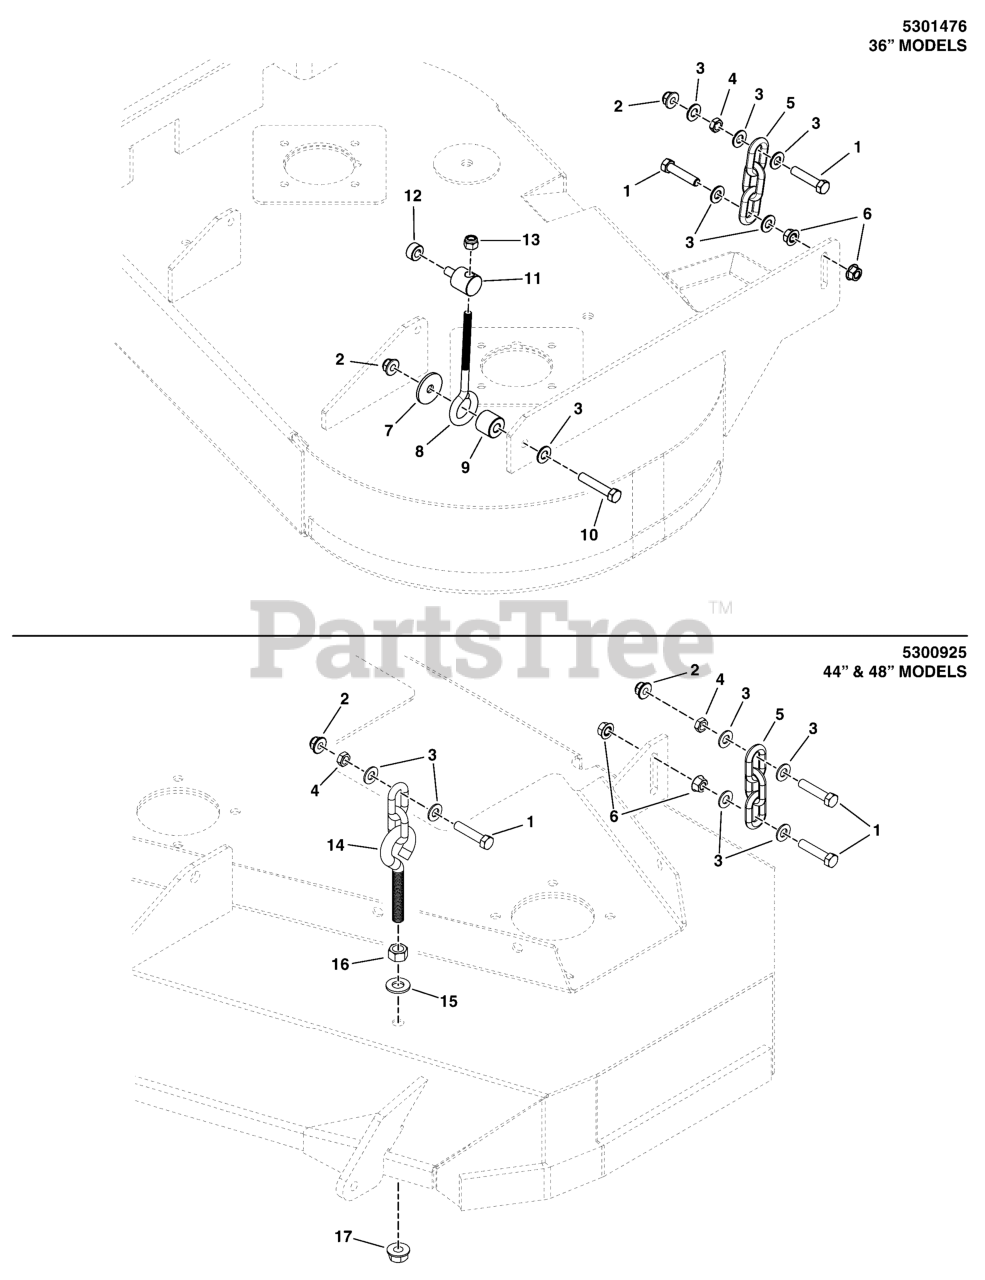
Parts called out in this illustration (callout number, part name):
1	BOLT, 3/8-16 X 1-3/4" GD5 CZ
2	NUT, 3/8-16 HEX NYLOCK FLANGE
3	WASHER, 3/8 SAE
4	NUT, 3/8-16 HEX JAM
5	CHAIN, 5/16 GD30, 3 LINKS
6	NUT, 3/8-16 HEX SERRATED FLANGE
7	WASHER, .390 X 1.50 X .109, YZ
8	EYE BOLT, 3/8-16X6,3THRD,1EYE,CZ, WELDED
9	SPACER, .39 X 1.00 X .88
10	BOLT, 3/8-16 X 2, GD5, CZ
11	ADJUSTER, BRAKE LINKAGE
12	COLLAR, 3/8 SET
13	NUT, 3/8-16 HEX NYLON LOCK
14	HANGER, FRONT DECK-2LINK, 5.5" EB
15	WASHER, 1/2 SAE
16	NUT, 1/2-13 HEX
17	NUT, Hex Flange, Nylock, 1/2-13
